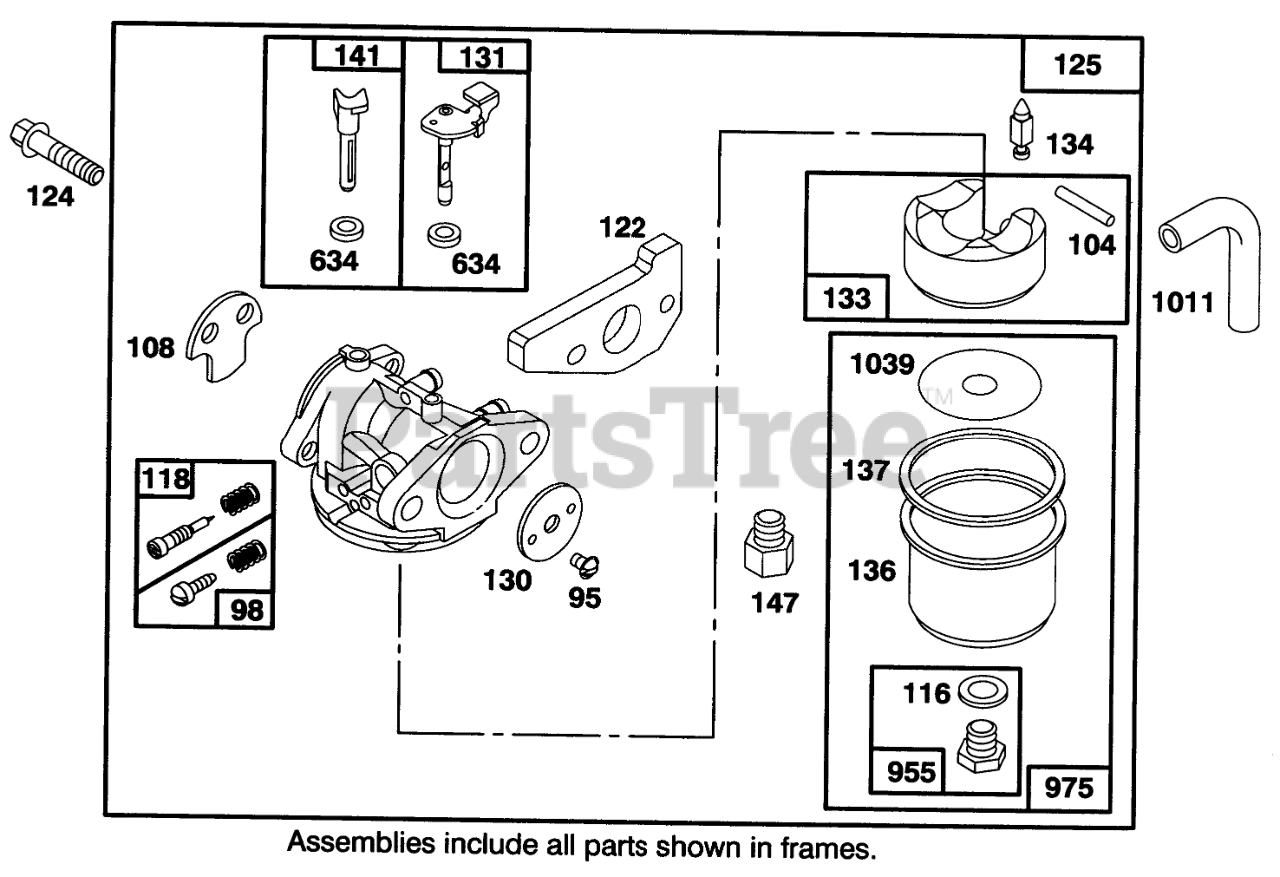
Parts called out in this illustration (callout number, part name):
95	SCREW - ROUND HEAD
98	IDLE ADJUSTING SCREW
104	FLOAT HINGE PIN
108	Valve-Choke
116	SEALING GASKET
118	VALVE KIT - NEEDLE
122	ADAPTER ASSEMBLY
124	HEX HEAD SCREW
125	CARBURETOR ASSEMBLY
130	THROTTLE VALVE
131	THROTTLE SHAFT
133	FLOAT-CARBURETOR
134	Valve-Inlet (Includes Seat)
136	FLOAT BOWL
137	FLOAT BOWL GASKET
141	CHOKE SHAFT
147	JET ADAPTER
634	SEAL WASHER
955	HEX HEAD SCREW
975	CARBURETOR BOWL ASM
1011	VENT TUBE
1039	FLOAT LIMITER
